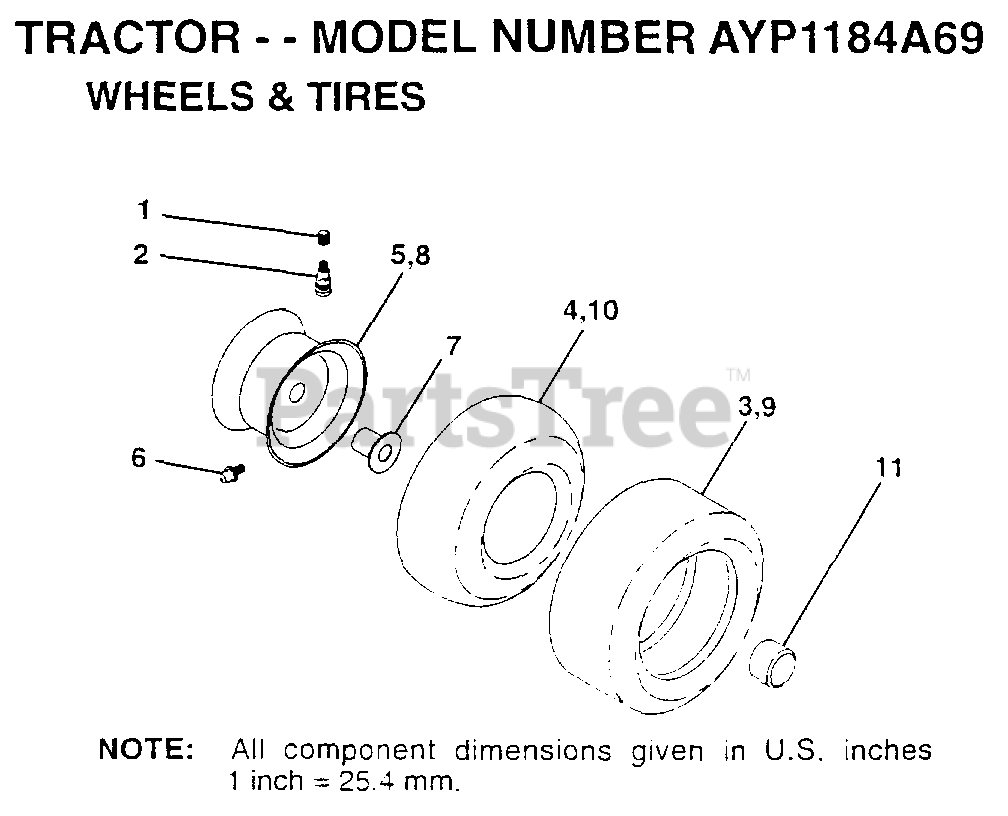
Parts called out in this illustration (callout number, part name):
1	VALVE CAP
2	VALVE STEM LT
4	TUBE.5.3/4.5/6
5	"RIM ASM 6"" FRT"
6	FITTING LT
7	"FLANGE, BEARING"
8	"RIM AS 8"" REAR"
9	TIRE.20X8-8
10	TUBE.18X9.5-8
11	HUB CAP
